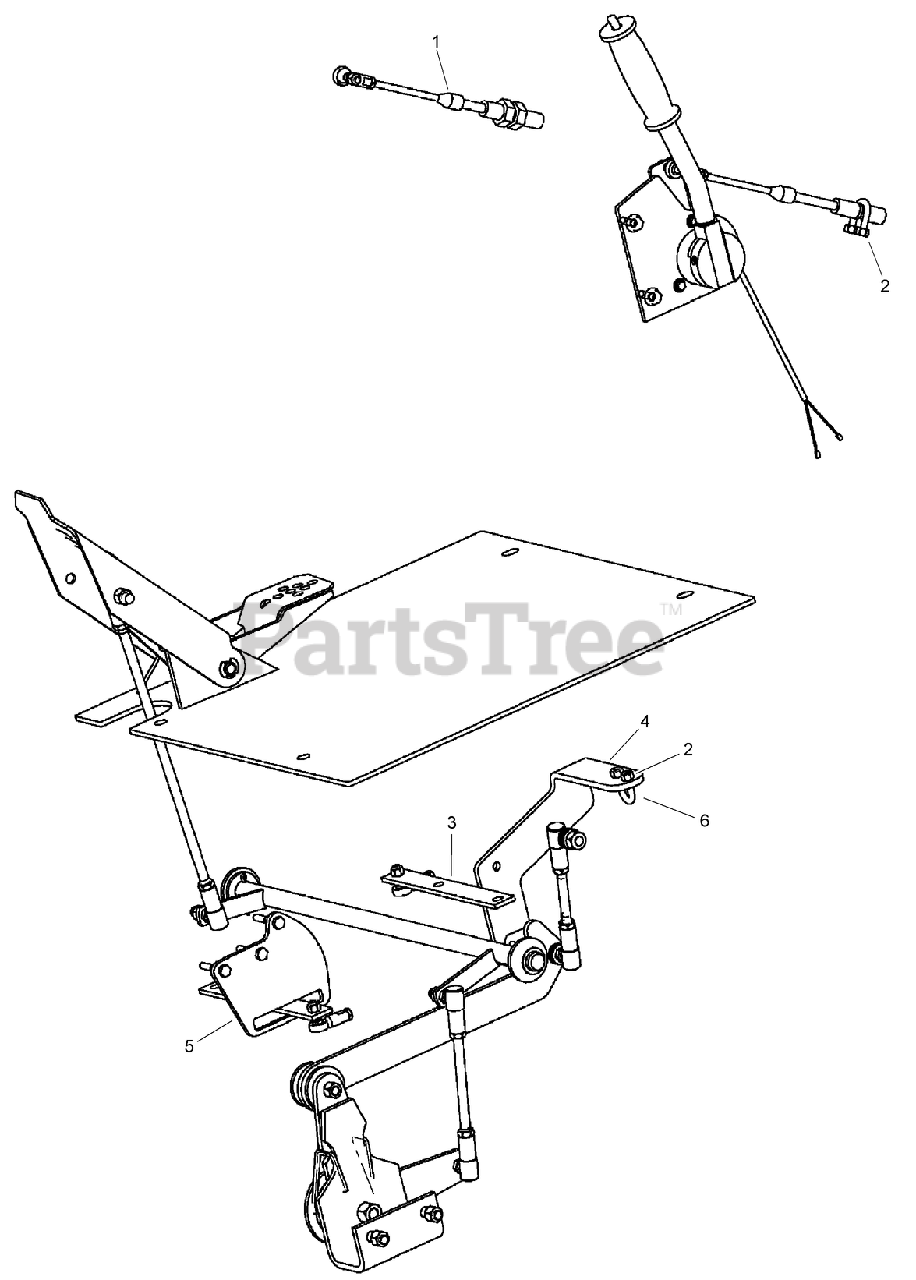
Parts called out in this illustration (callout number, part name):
1	GROUND DRIVE CONTROL CABLE ASM
2	NUT-Prev Trq 1/4 GRC PHC Direct
3	LEVER-Pump Control
4	PLATE-Mount
5	STOP-Pump Lever
